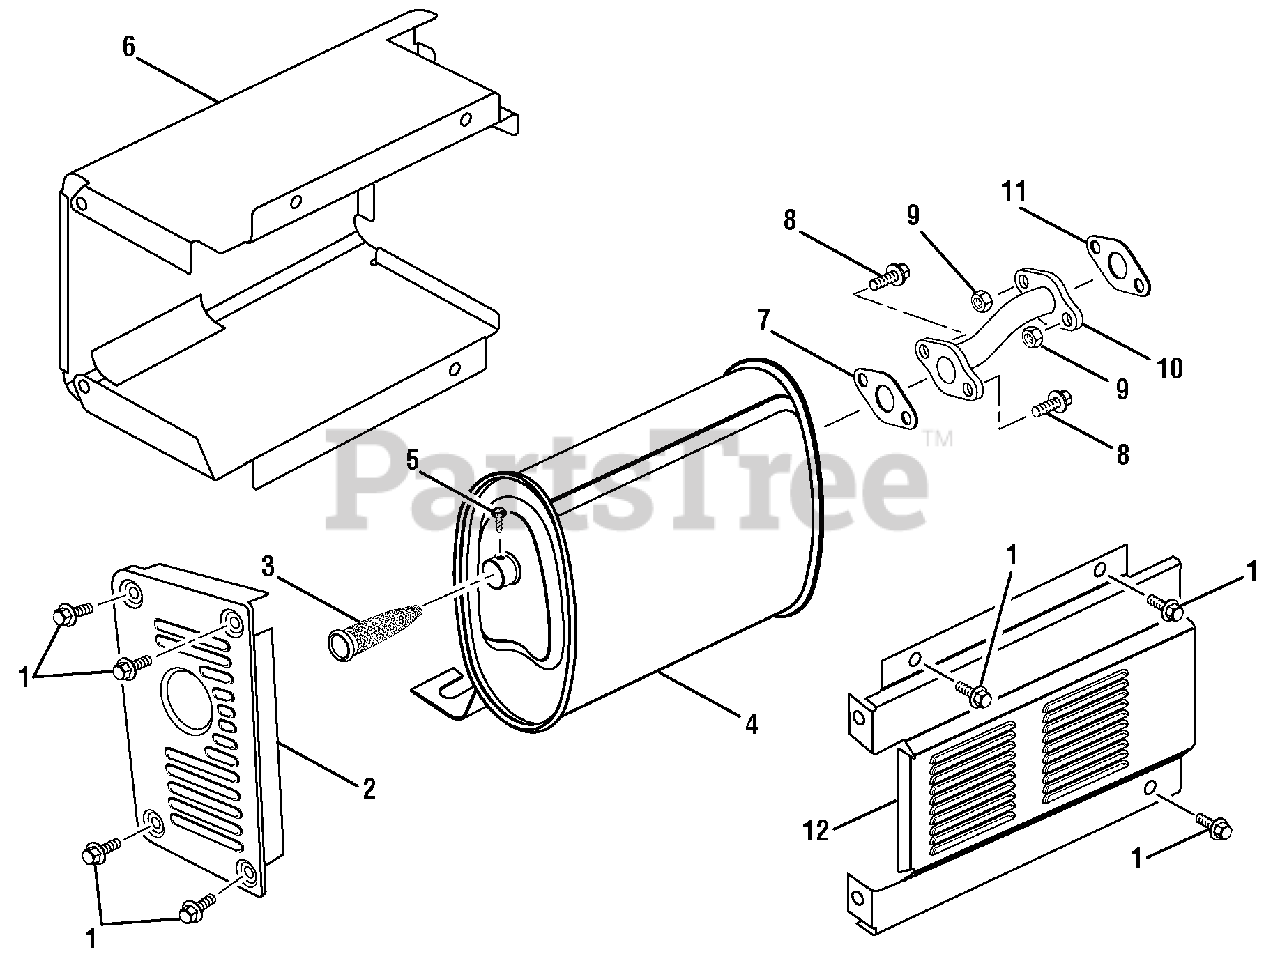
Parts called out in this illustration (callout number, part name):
1	Bolt (M8 x 16 mm, Flange Hd.)
2	Side Cover
3	Spark Arrestor
4	Muffler Assembly
5	Set Screw
6	Inner Cover
7	Exhaust Gasket (Engine)
8	Flange Bolt (M8 x 25 mm)
9	Hex Nut (M8)
10	Manifold (Exhaust)
11	Gasket (Exhaust, Muffler Side)
12	Outer Cover
